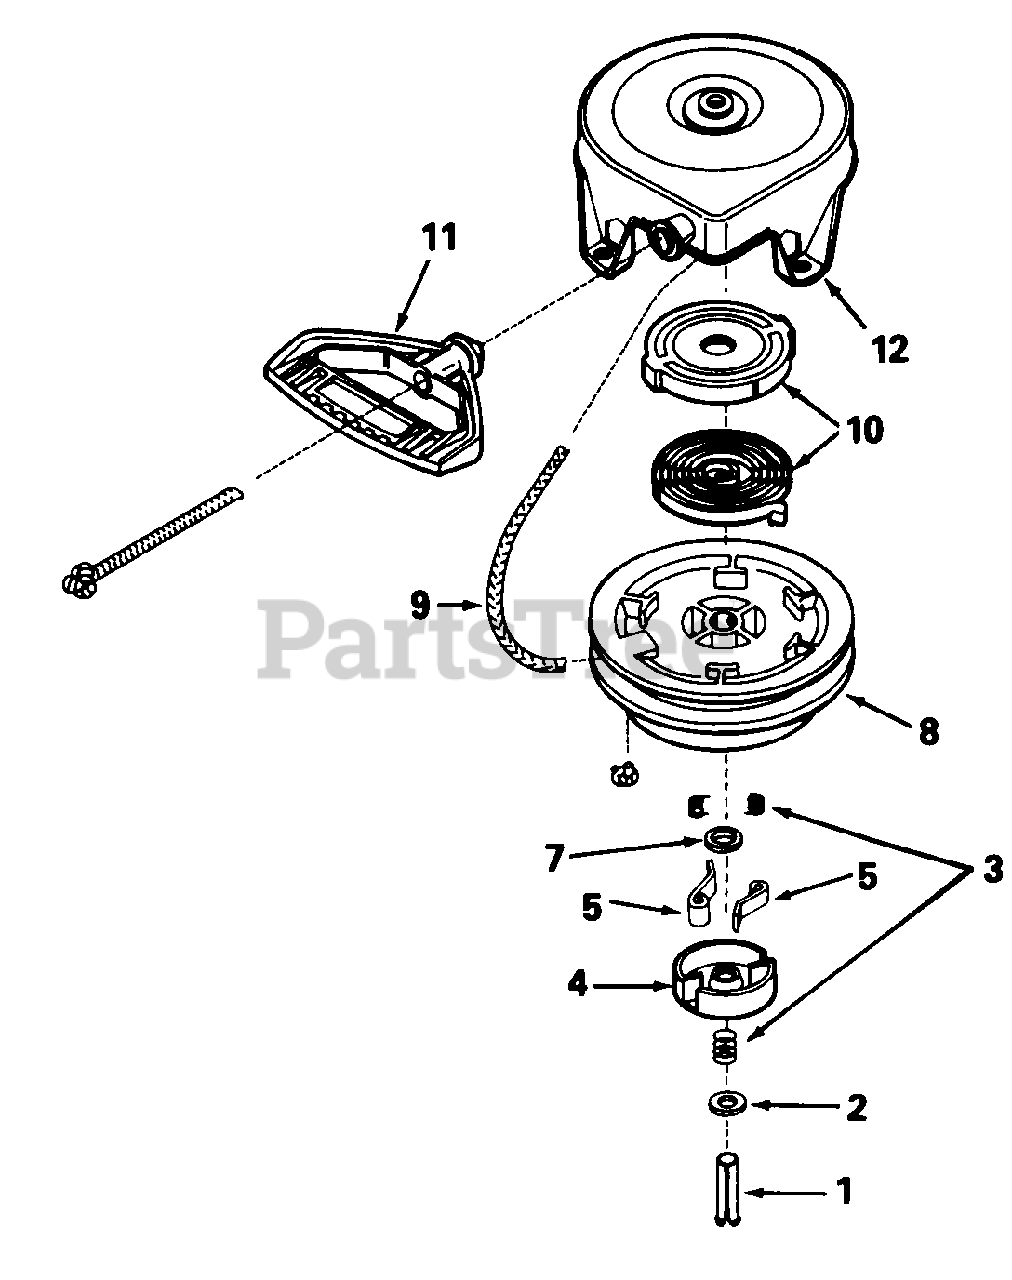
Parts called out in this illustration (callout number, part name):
1	Pin, Spring
3	Spring Ass'y., Brake and Dog
5	Dog, Starter
9	Rope, Starter
10	Spring & Keeper Ass'y.
11	Handle, Mitten Grip
12	Housing Ass'y., Starter
